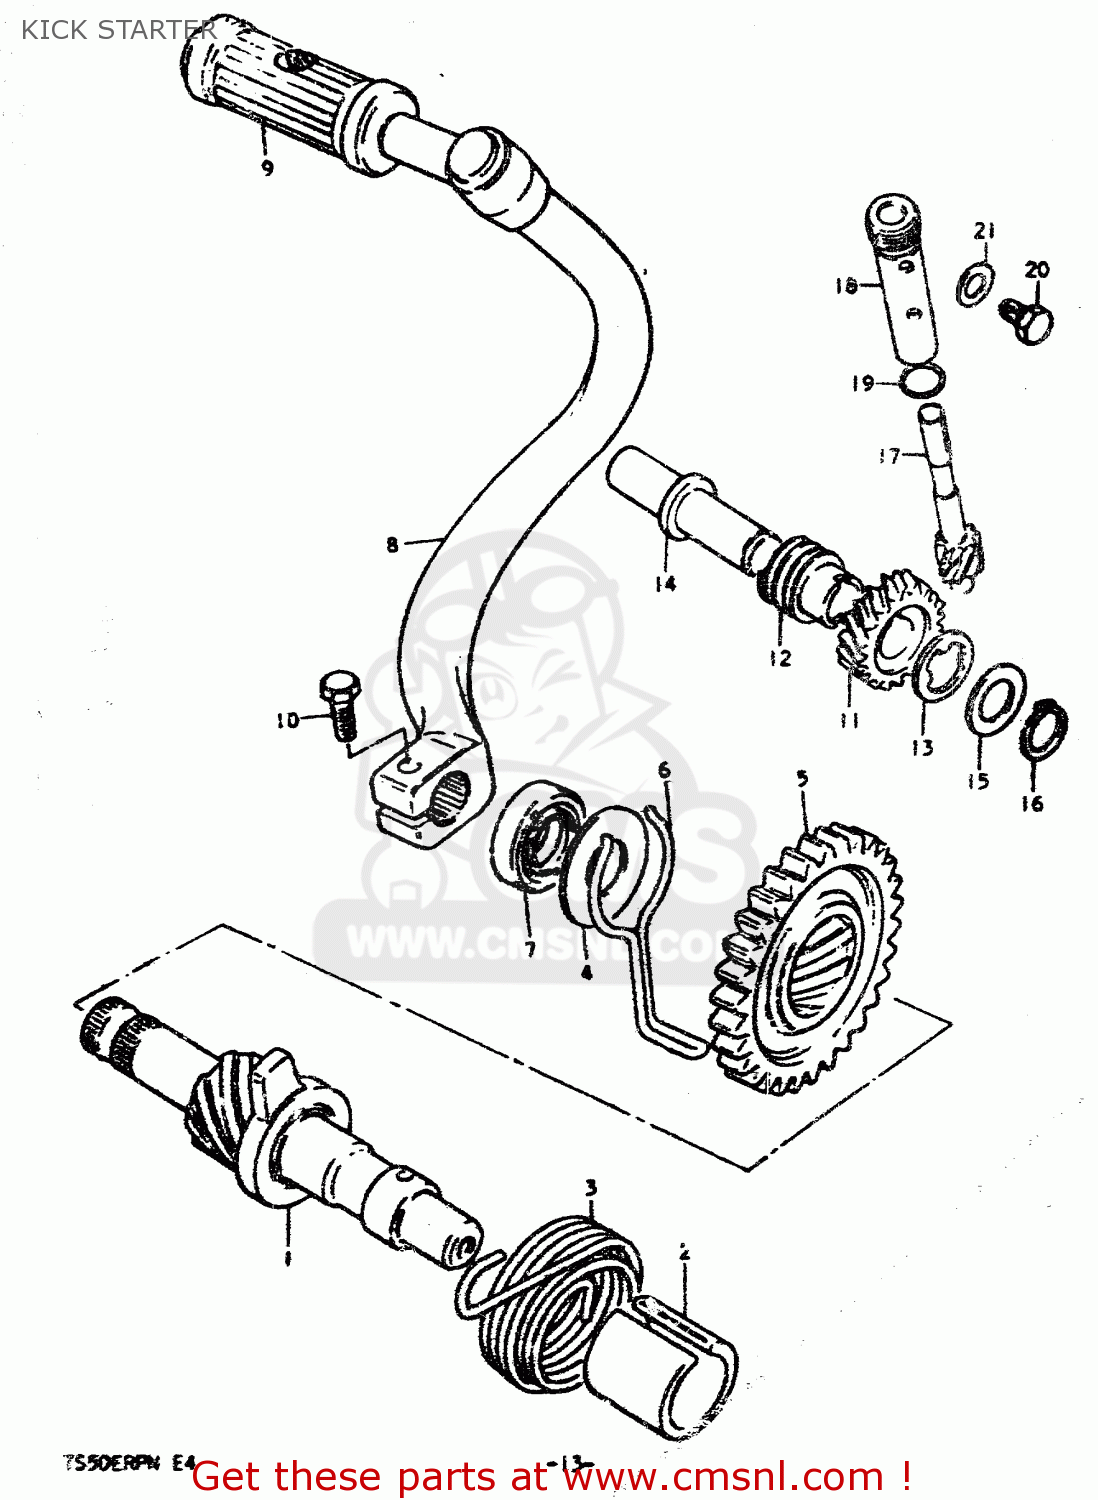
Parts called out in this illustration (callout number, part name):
1	SHAFT,KICK STARTER
2	GUIDE,KICK STARTER SFT SPRING
3	SPRING
4	WASHER
5	GEAR,KICK STARTER DRIVE(NT:30)
6	RETAINER,SNAP
7	SEAL,OIL(14X24X6)
8	LEVER ASSY, KICK STARTER
9	RUBBER,KICK STARTER PEDAL
10	BOLT
11	GEAR, TACHOMETER DRIVE NO.2
12	GEAR,TACH DRIVE NO.2(NT:3)
13	RETAINER,TACH DRIVEN GEAR NO1
14	SHAFT,TACHOMETER DRIVEN GEAR
15	WASHER,THRUST
16	CIRCLIP
17	GEAR,TACHOMETER DRIVEN(NT:12)
18	SLEEVE
19	O RING(D:1.3,ID:9.6)
20	BOLT
21	WASHER
